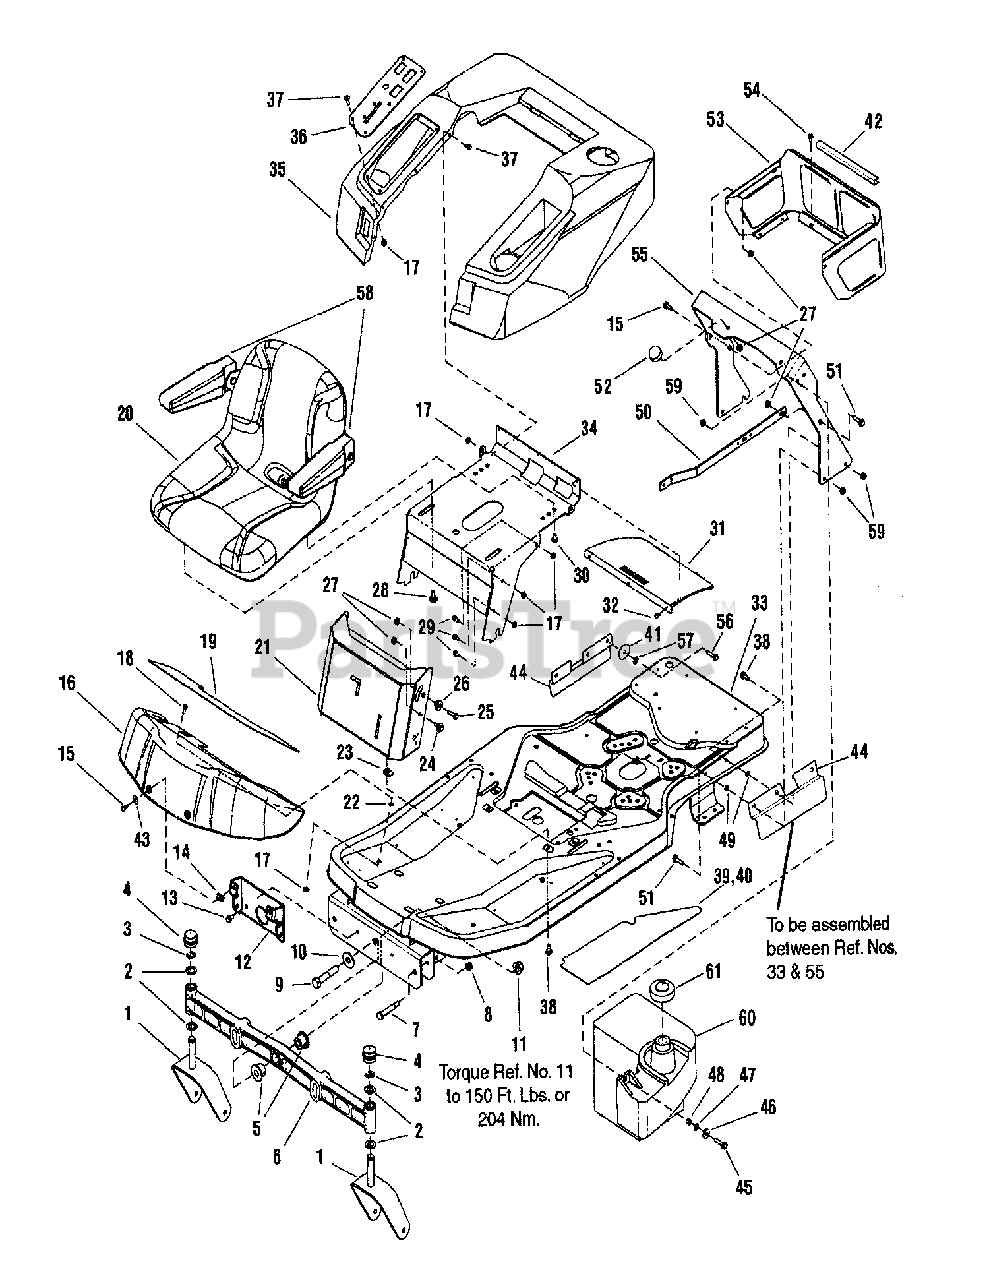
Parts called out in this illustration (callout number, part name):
1	WELDMENT, Caster Yoke & Spindle- Black
2	WASHER, .75 ID x 1.60 OD x .05 Thick Flat (Black)
3	KLIPRING, External for .750 Dia. Shaft
4	CAP, Hub 1.481 I.D. x .62 Long Red Poly
5	BUSHING, Axle Pivot PM Yellow
6	AXLE, Front Iron Casting Machined ZT
7	SHOULDER BOLT, 3/8-16 x 3" Long .50 Sh GR5 Black
8	NUT, 3/8-16 Hex Flange Nyloc
9	SCREW, 5/8-11 x 3-1/4" Hex Head Cap, GR5 Yellow
10	WASHER, 0.64 I.D. x 1.75 O.D. x .11 Thick, Black
11	NUT, Hex Flange 5/8-11 Two Way Lock Yellow
12	BRACKET, Footrest Support, Black
13	SCREW, 5/16-18 x .62 Taptite
14	SPEED NUT, 1/4-20 Lug Type .025/.150 Black
15	SCREW, 5/16-18 x 1" Hex Head Cap
16	PANEL, Footrest, ZT 7000, Red
17	NUT, 1/4-20 Hex Flange Nyloc, Black
18	BOLT, 1/4-20 x 2" Round Head Short Square Neck, GR5, Black
19	PAD, Footrest Center Black Vinyl
20	ASSEMBLY, Seat w/Arm Rests
21	PANEL, Front - Manual Brake & Deck Lift
22	RETAINER, 1/4" Bolt
23	NUT, Speed, Lug Type, 5/16-18
24	SHOULDER BOLT, 5/16-18
25	BOLT, 5/16-18 x 1-1/4" Round Head Short Square Neck GR5, Black
26	PIVOT, Hood (Powdered Metal)
27	NUT, 5/16-18 Hex Flange Lock, Small - Black
28	BOLT, 5/16-18 Idler Pivot
29	SCREW, 1/4-20 x 5/8" Hex Whiz Lock Flange
30	SCREW, 5/16-18 x 3/4" Hex Flange Lock Dog Point
31	SCREEN, Deck Top
32	RIVET, .188 x .617 Large Flange
33	WELDMENT, Frame - 42" & 50" ZT (Black)
34	SUPPORT, Seat Deck, ZTS - Black
35	SEAT DECK, Red Poly, ZTS - Red
36	PLATE, Control, ZTS - Black
37	SCREW, 1/4-20 x 3/4" Truss Head Torx Black
37	SCREW, 1/4-20 x 3/4" Hex Flange Lock Black
38	BOLT, 5/16-18 x 1" Hex Flange Lock YZ
39	PAD, Footrest RH Black Vinyl w/Adhesive
40	PAD, Footrest LH Black Vinyl w/Adhesive
41	WASHER, .375 Flat (0.41 I.D. x 1.50 O.D. x .25 Thick) Black
42	TRIM, 8"
43	WASHER, 5/16" External Tooth Lock Washer, Yellow
44	GUARD, Debris, ZTR - Black
45	SCREW, 5/16-18 x 1-1/2" Hex Head Cap, GR5, Black
46	WASHER, 5/16" Flat (.341 I.D. x 1.00 O.D. x .13 Thick) Black
47	WASHER 5/16" Internal/External Tooth Lock, BZ
48	SPACER, .316 x .375 x .300/.310
49	PUSH NUT, 5/16" Dia. Thread .625 O.D. Black (Pal)
50	STRAP, Fuel Tank Brace
51	SCREW, 5/16-18 x 1-1/4" Hex Head Cap, GR5, Black
52	BUMPER, Rubber 1.50 DIA 0.5 Thick
53	SHROUD, Rear, ZTR 14+16, Cor, Black
54	SCREW, 1/4-20 x 1/2" Hex Washer Head Screw Black (Taptite)
55	SUPPORT, Seat Deck - Black
56	SCREW, 3/8-16 x 1-1/4" Hex Head Cap, GR5, Black
57	PUSH NUT, .375 Dia. Thread .781 O.D. Black (Pal)
58	KIT, Arm Rest L.H. & R.H.
59	NUT, 5/16-18 Hex Flange Nyloc
60	ASSEMBLY, Fuel Tank (incl. below items 61 thru 64)
61	ASSEMBLY, Fuel Cap (Vented)
